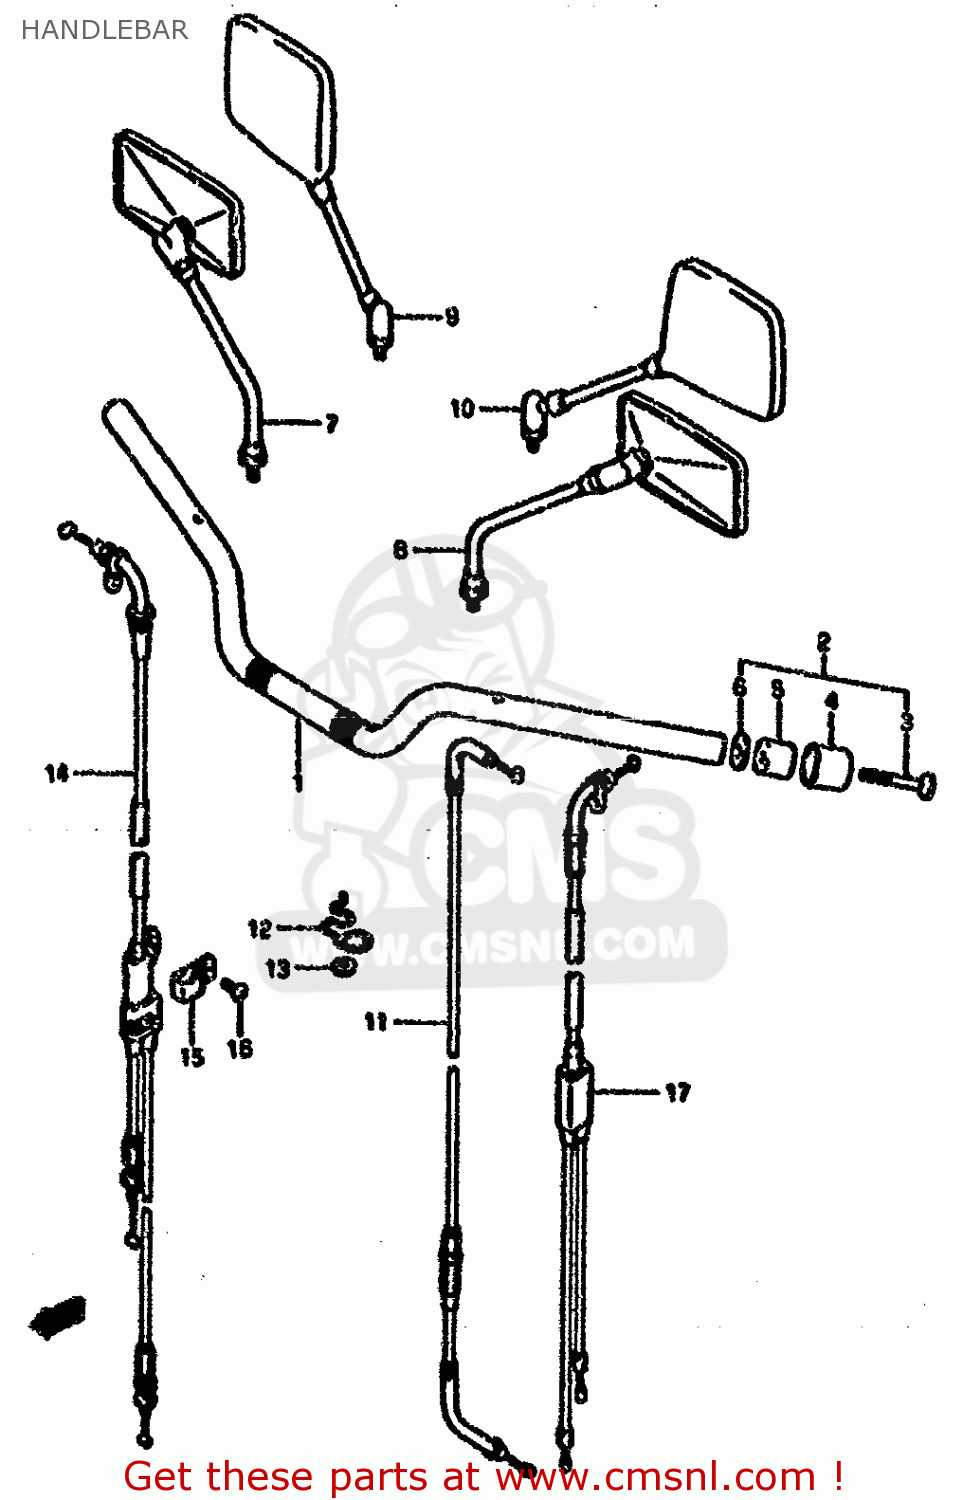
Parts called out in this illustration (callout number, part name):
1	HANDLEBAR
2	BALANCER SET,HANDLEBAR
3	SCREW
4	CAP,BALANCER
5	BALANCER,HANDLEBAR
6	SPACER,BALANCER
7	MIRROR ASSY,RR VIEW,R
8	MIRROR ASSY,RR VIEW,L
9	MIRROR ASSY,R.
10	MIRROR ASSY,L.
11	CABLE ASSY,CLUTCH
12	GUIDE,CLUTCH CABLE
13	WASHER
14	CABLE ASSY,THROTTLE
15	CLAMP,THROTTLE CABLE
16	SCREW
17	CABLE,STARTER
